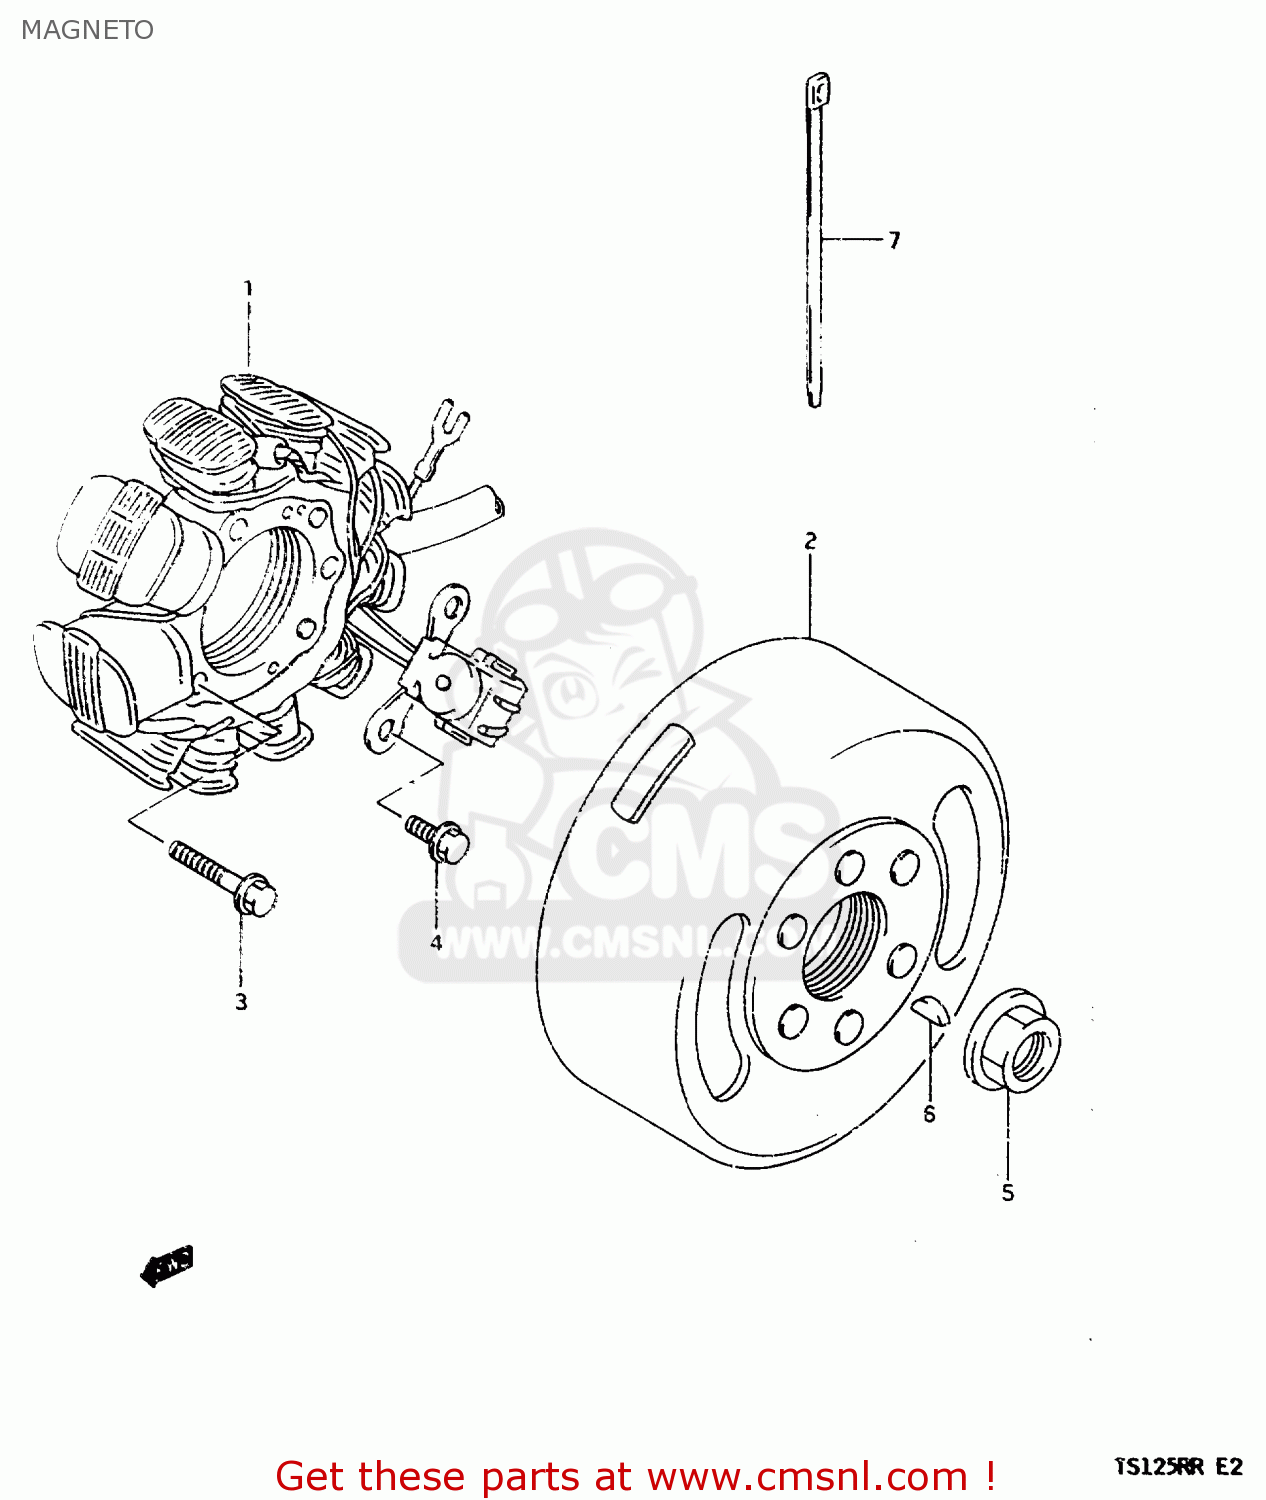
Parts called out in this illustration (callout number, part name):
1	STATOR ASSY
2	ROTOR ASSY
3	BOLT
4	BOLT
5	NUT
6	KEY
7	CLAMP(L:145)
